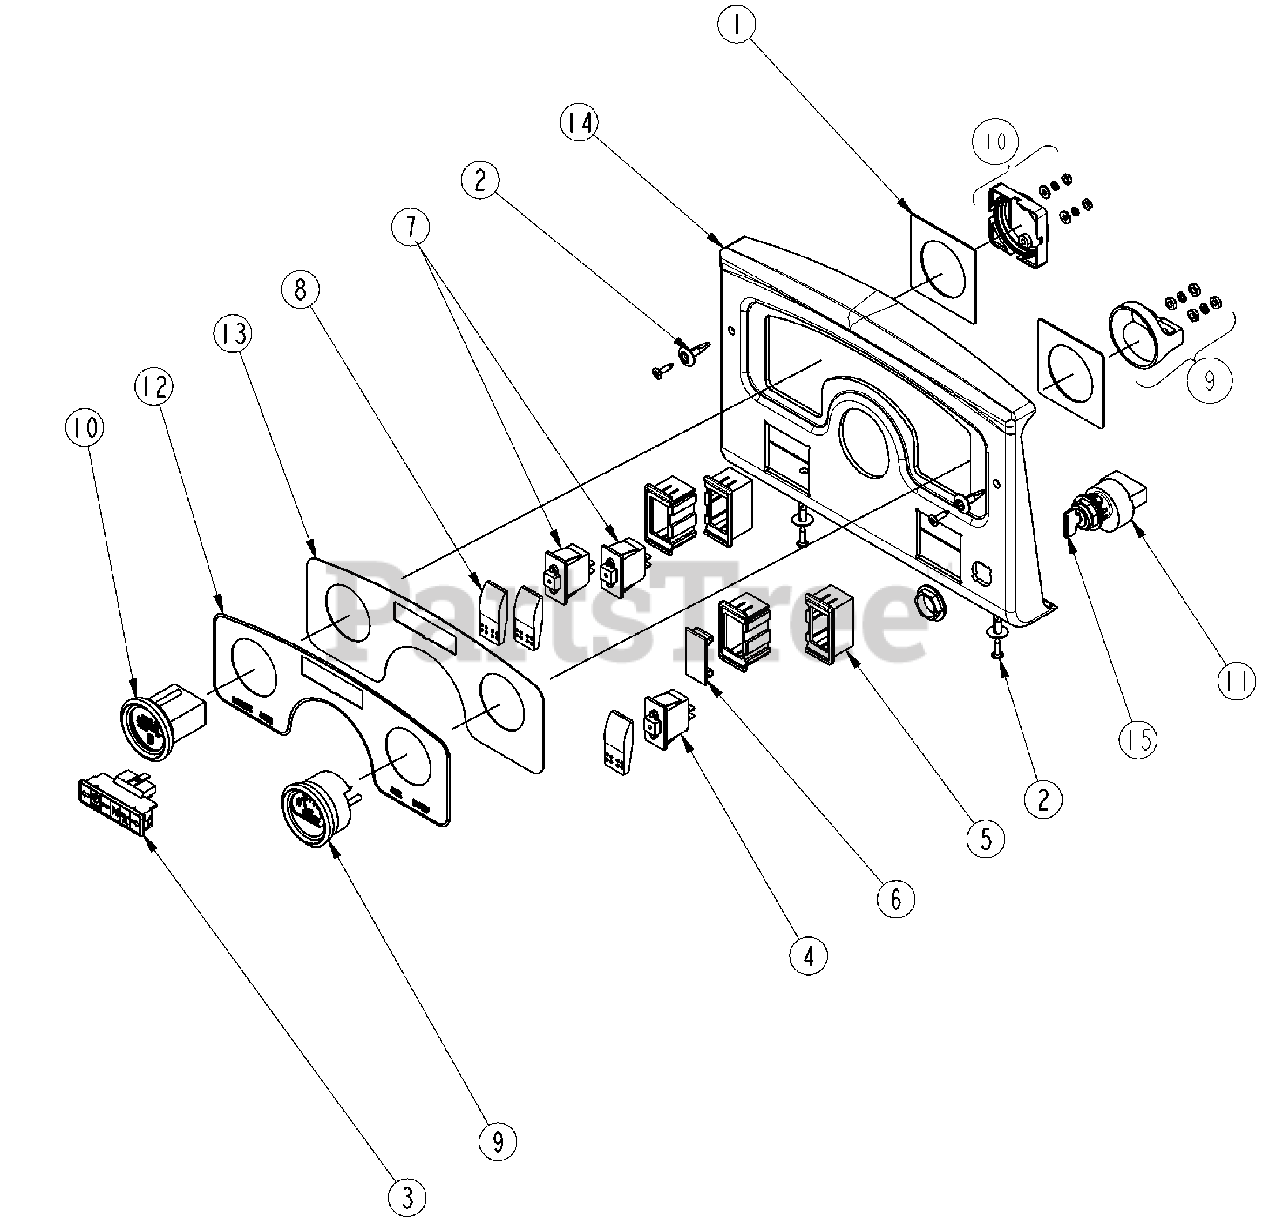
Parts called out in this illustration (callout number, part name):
1	DASH BACKER PLATE
2	RIVET, 1/4
3	INDICATOR LIGHT STRIP 8-PIN Replacement Bulb 833-418c
4	DUMP SWITCH WAYTEK 44304
5	SWITCH MOUNT END
6	PANEL PLUG
7	SWITCH ROCKER SPST
8	SWITCH ACTUATOR
9	GAUGE, VOLT METER
10	GAUGE, HOUR METER
11	IGNITION SWITCH W/2 KEYS(6PIN)
12	DECAL INSTR. PANEL TRUCK 4X4
13	INSTRUMENT PANEL
14	DASH TRUCK
15	KEY W/SHIELD (RP FOR 833-336C)
